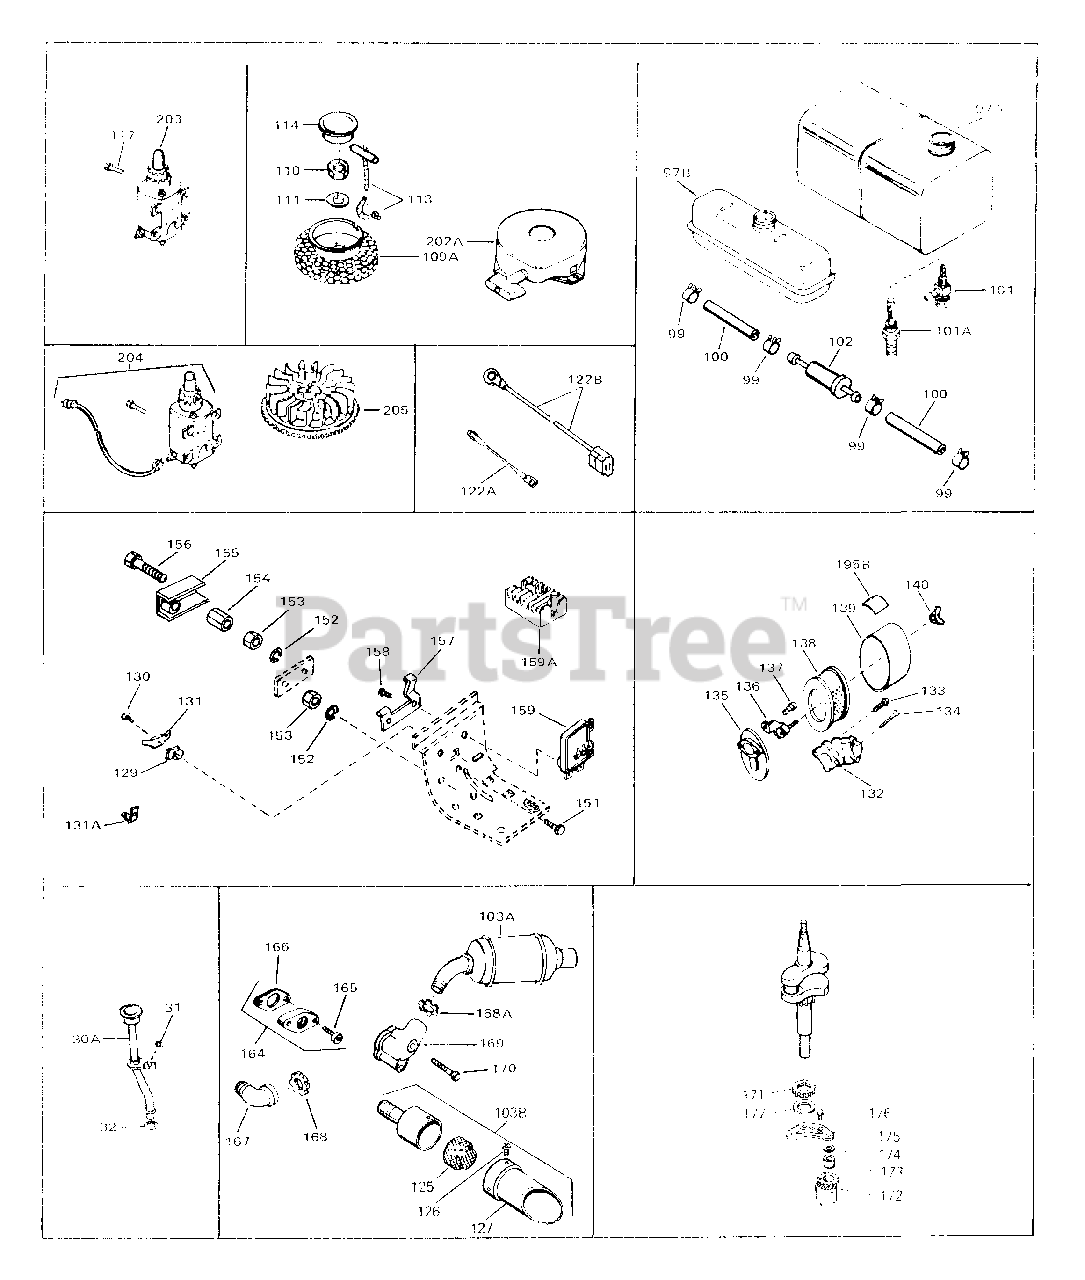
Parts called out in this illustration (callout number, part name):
100	Line, Fuel (Braided 8-1/4")
100	Line, Fuel (Braided 16")
100	Line, Fuel (Braided 32")
103B	Muffler
111	Washer, Belleville
114	Plug, Screen
117	Screw, Hex hd. Sems, 1/4-20 x 1/2
125	Screen, Muffler
126	Screw, Hex hd. self-tap, 8-18 x 3/8
127	Cover & Tube, Muffler
151	Screw, Phil. rd. hd., 5-40 x 9/16
152	Lockwasher
154	Nut, Hex, 5-40
155	Cover, Rectifier panel
164	Kit, Muffler adapter
165	Screw, Fil. hd. mach., 5/16-18 x 3/4
166	Gasket, Exhaust
203	Motor, Starter (12 Volt)
204	Starter Motor Kit (110-120 Volt)
205	Flywheel
